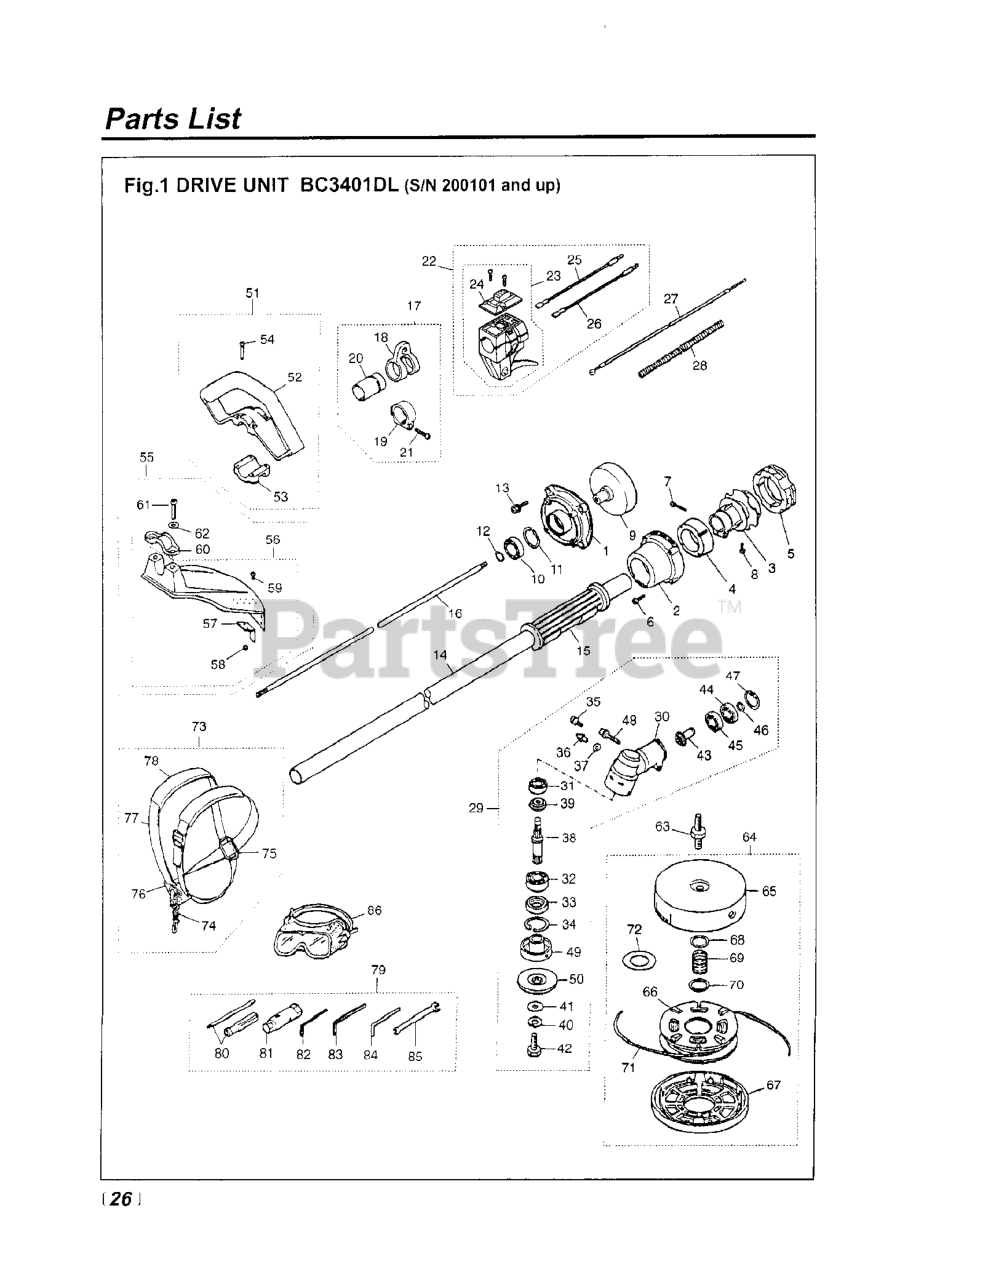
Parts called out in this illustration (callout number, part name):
4	ABSORBER
5	ABSORBER
7	BOLT, M6 x 30
8	BOLT M5 X L10 ALLEN BOLT
9	DRUM
10	BEARING 0600406202
11	SNAP RING
12	RING, SNAP, M15 x 1.0
14	PIPE COMP.
17	HANGER ASSEMBLY
25	CORD (A), BLACK
26	CORD (B), RED
27	CABLE-COMP
28	TUBE
29	GEAR CASE ASSY(RPLS T300313000
30	GEARCASE
33	OIL SEAL
35	BOLT M5 X L10 ALLEN BOLT
39	GEAR
42	BOLT M8 X L25 L/H
43	PINION
44	BEARING,10MM ID,26MM OD,8MM W
47	RING,SNAP M26x1.2 RP-318013340
49	HOLDER(A)
50	HOLDER (B)
51	HANDLE ASSEMBLY
55	GUARD ASSY RP-4001,4100,4101)
56	GUARD COMP
57	BLADE
63	SHAFT.M8
64	RedMax TBD
66	CORD HOLDER
76	HANGER COMP
79	TOOL SET
83	Wrench Tool
